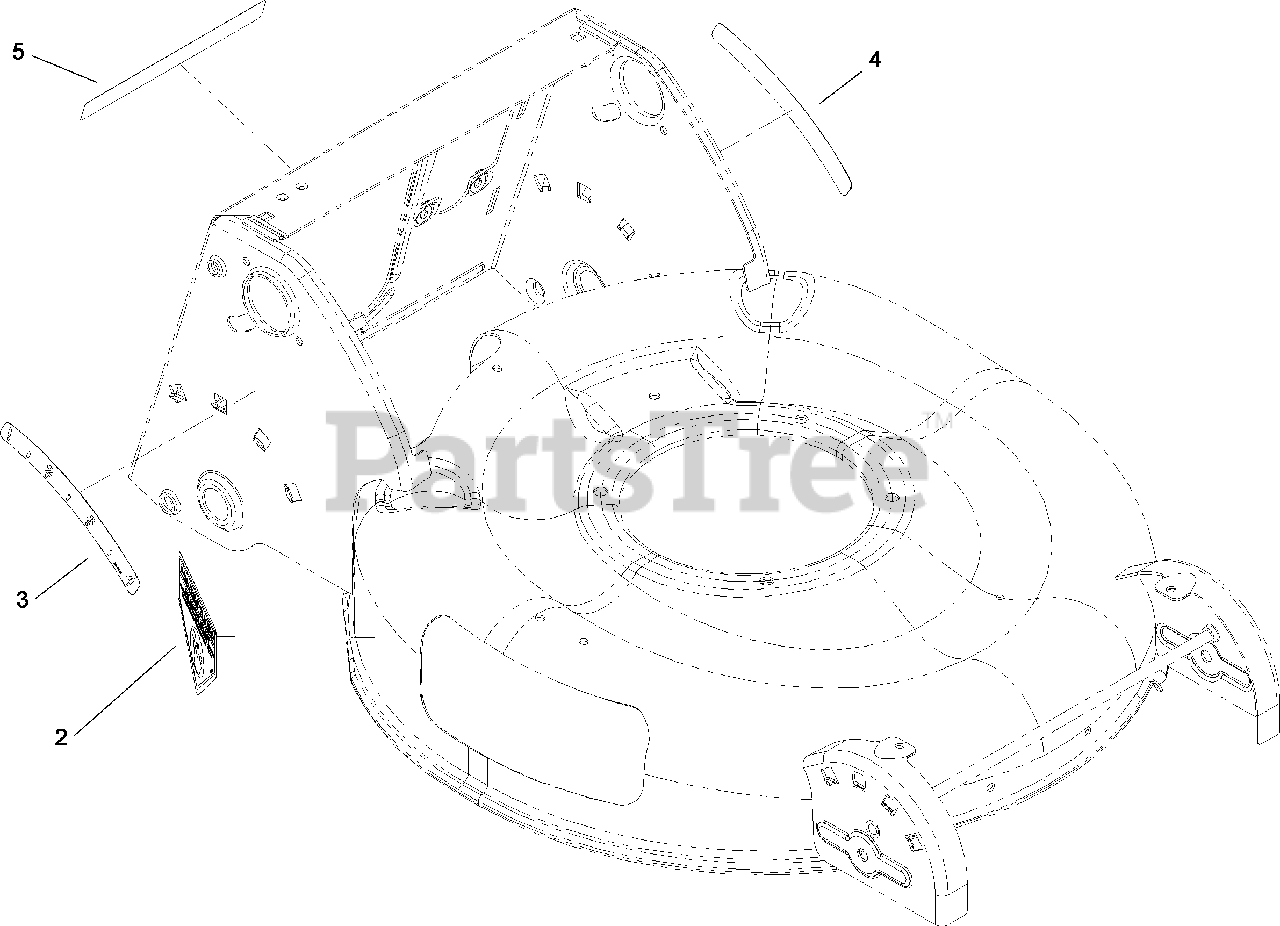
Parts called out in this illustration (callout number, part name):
2	DECAL-DANGER
3	DECAL-HOC, RH
4	DECAL-HOC, LH
5	DECAL-SAFETY
